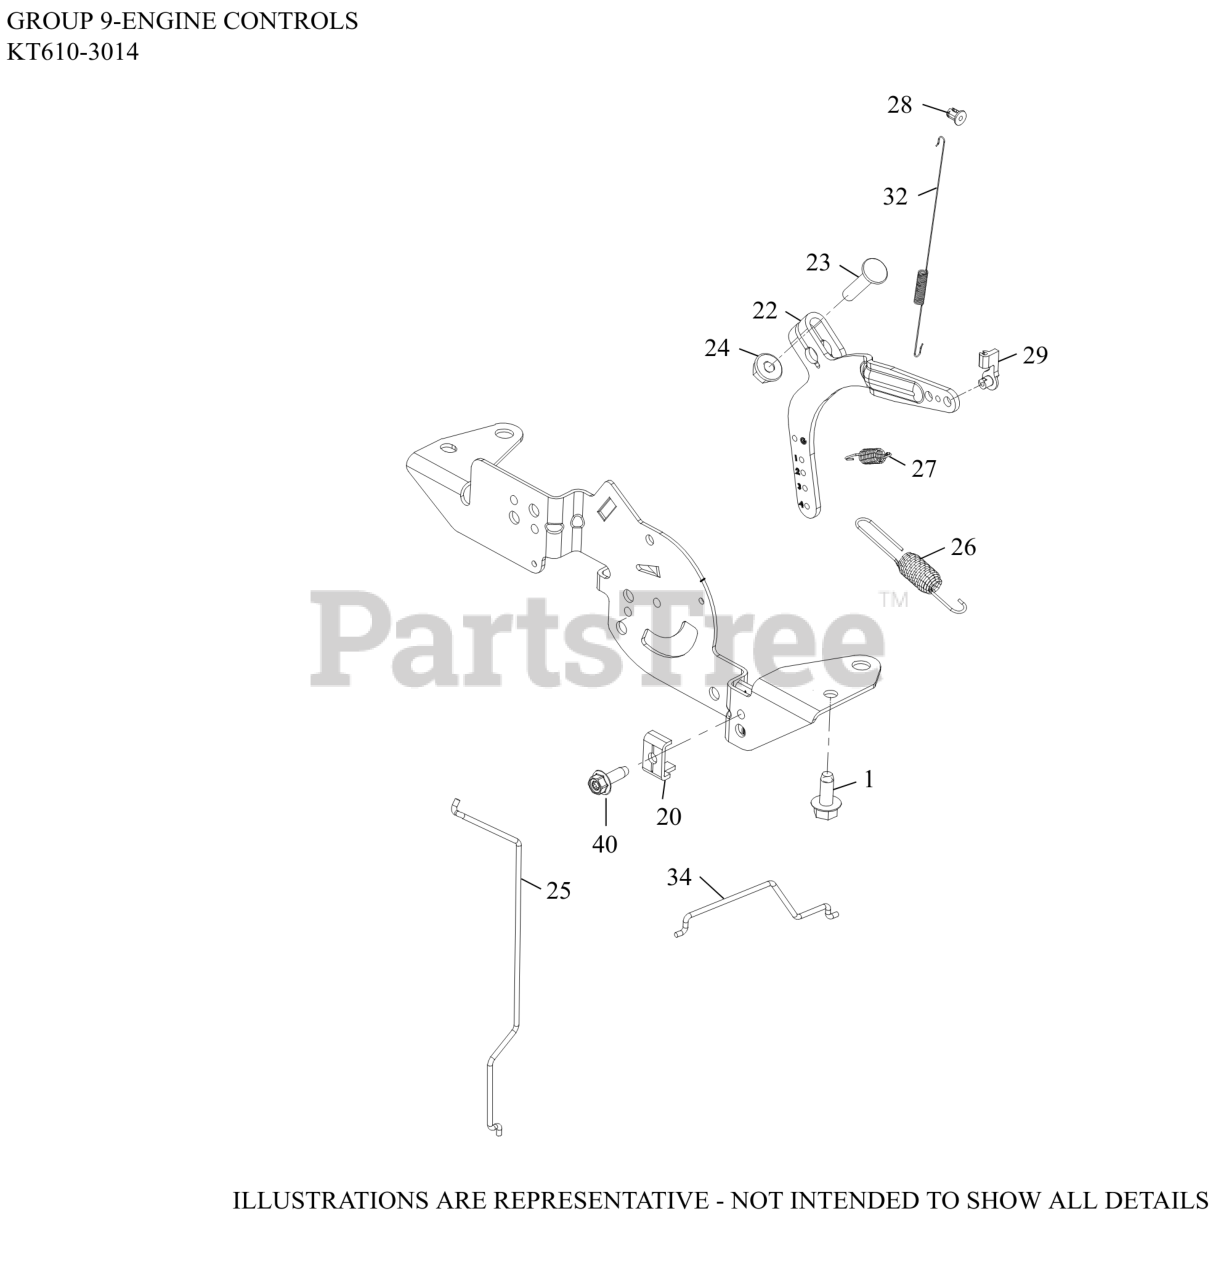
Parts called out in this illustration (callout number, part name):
1	SCREW, THREAD FORMING
20	CLAMP, CABLE-(#2523753S)
22	LEVER, GOVERNOR - (#2409069S)
23	BOLT, RD HD SQ NECK M6X1.0X25
24	NUT, FLANGE 1/4-20
24	NUT, FLG M6X1.0
25	LINKAGE, CHOKE
26	SPRING, GOVERNOR (ORANGE)
27	SPRING, GOVERNED IDLE
28	BUSHING, LINKAGE RETAINING
29	BUSHING, THROTTLE LINKAGE
32	SPRING, LINKAGE
34	LINKAGE, THROTTLE
40	SCREW, THREAD FORMING
